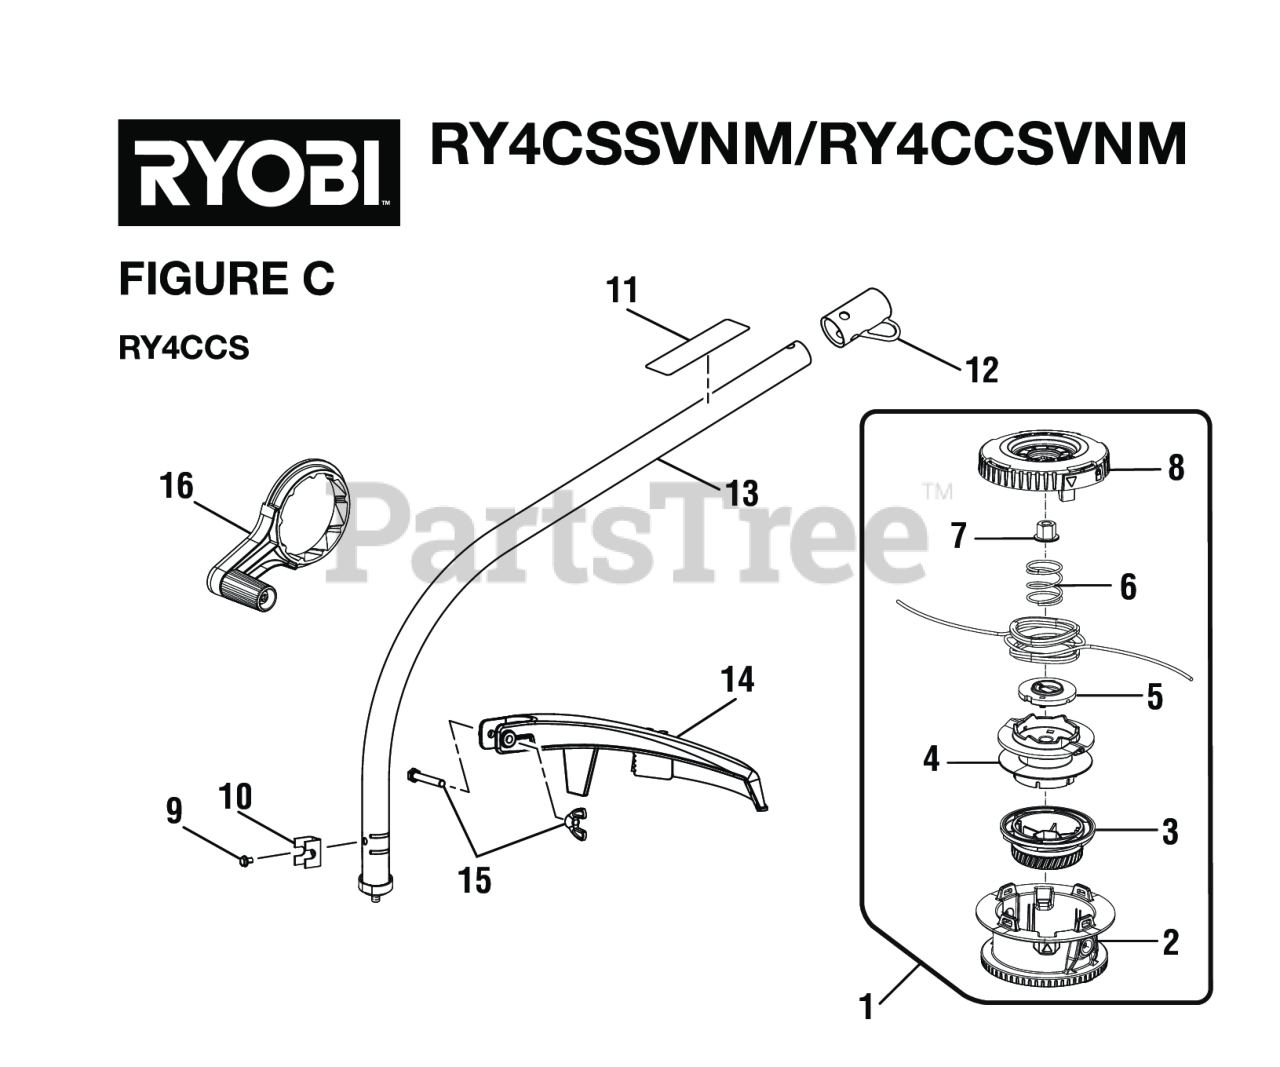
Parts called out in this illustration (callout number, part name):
1	Trimmer Head Assembly (.095) (Inc. Key Nos. 2-8)
2	Bump Head
3	Bump Knob (Green)
4	Spool Assembly
5	String Guide
6	Compression Spring
7	Flange Nut (M8)
8	Locking Assembly
9	Screw (#10-32 x 3/8 in., Hex Washer Hd. S.T.)
11	Warning Icon Label
12	Storage Hanger Cap
13	Curved Shaft Assembly (Inc. Key Nos. 9-12)
14	Grass Deflector Assembly
15	Fastener Parts Kit
16	Crank Handle
